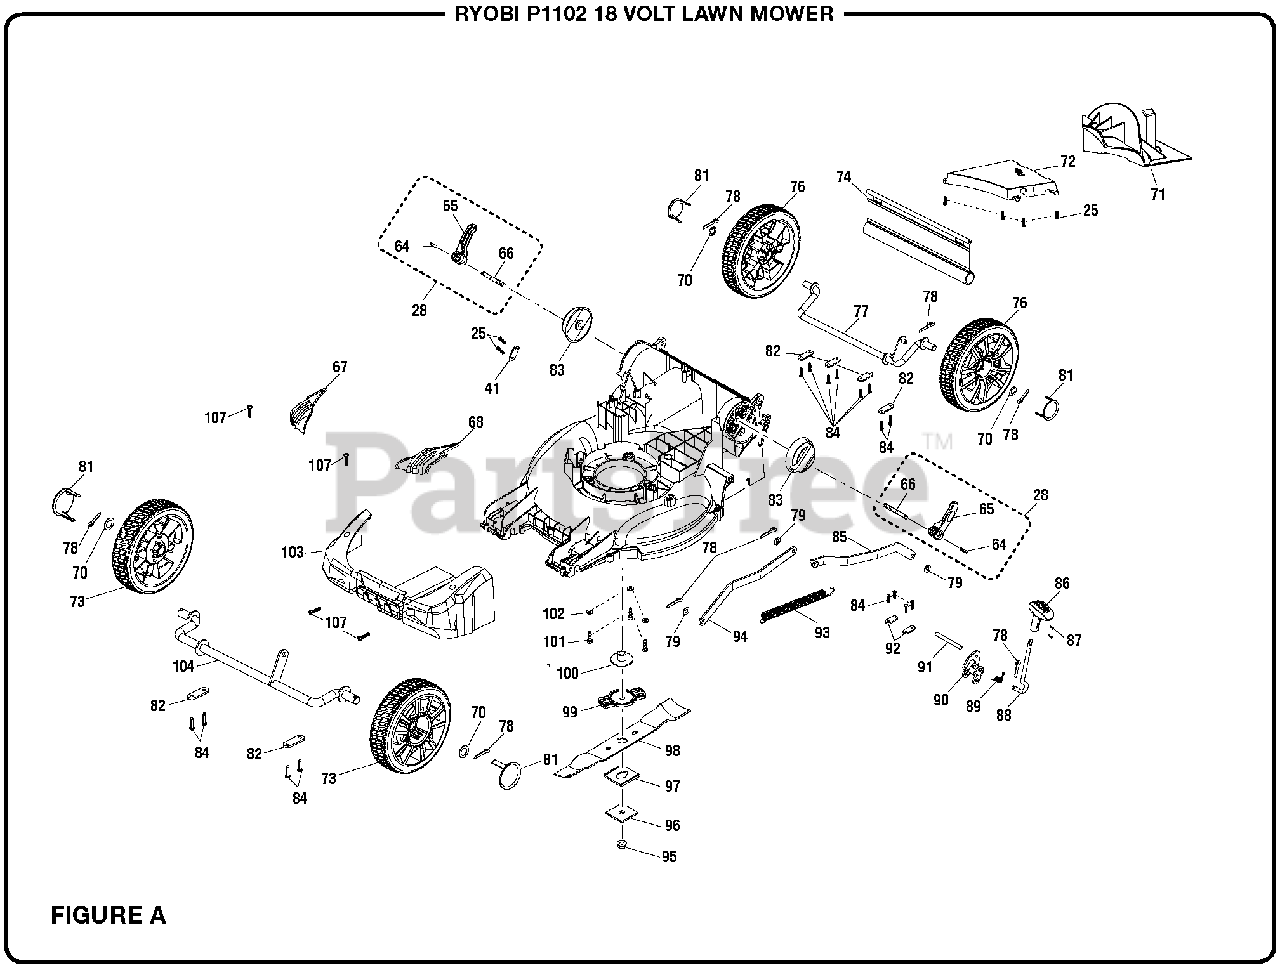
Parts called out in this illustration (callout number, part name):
25	Screw (M4 x 16 mm, T20 Torx Pan Hd.)
28	Handle Lock Assembly
41	Cord Clip
64	Spring Pin
66	Quick Lock Press
67	Grass Protector (Right)
68	Grass Protector (Left)
70	Washer (OD20 x ID13 x 1t)
71	Mulching Plug
72	Rear Cover
73	Front Wheel
74	Rear Skirt
76	Rear Wheel w/Bearing & Cap
77	Rear Wheel Axle
78	Cotter Pinφ (2.5)
79	Washer (OD18 x ID8.4 x 1t)
81	Wheel Cover
82	Axle Pressure Plate
83	Base (Lock Handle)
84	Screw (M4 x 18 mm, Torx Pan Hd.)
85	Rear Lift Rod
86	Height Adjustment Handle
87	Screw (M3 x 9 mm, Flat Hd.)
88	Height Adjustment Lever
89	Torsion Spring (Height Adjustment)
90	Height Adjustment Bracket
91	Axle (Height Adjustment)
92	Pressure Plate (Height Adjustment)
93	Retention Spring
94	Front Lift Rod
95	Blade Nut (M10)
96	Blade Retainer
99	Blade Holder
100	Motor Shaft Bushing
101	Bolt (M6 x 16 mm, Hex Hd.)
102	Washer (OD15 x ID6 x 1t)
104	Front Wheel Axle
107	Screw (M4 x 20 mm)
